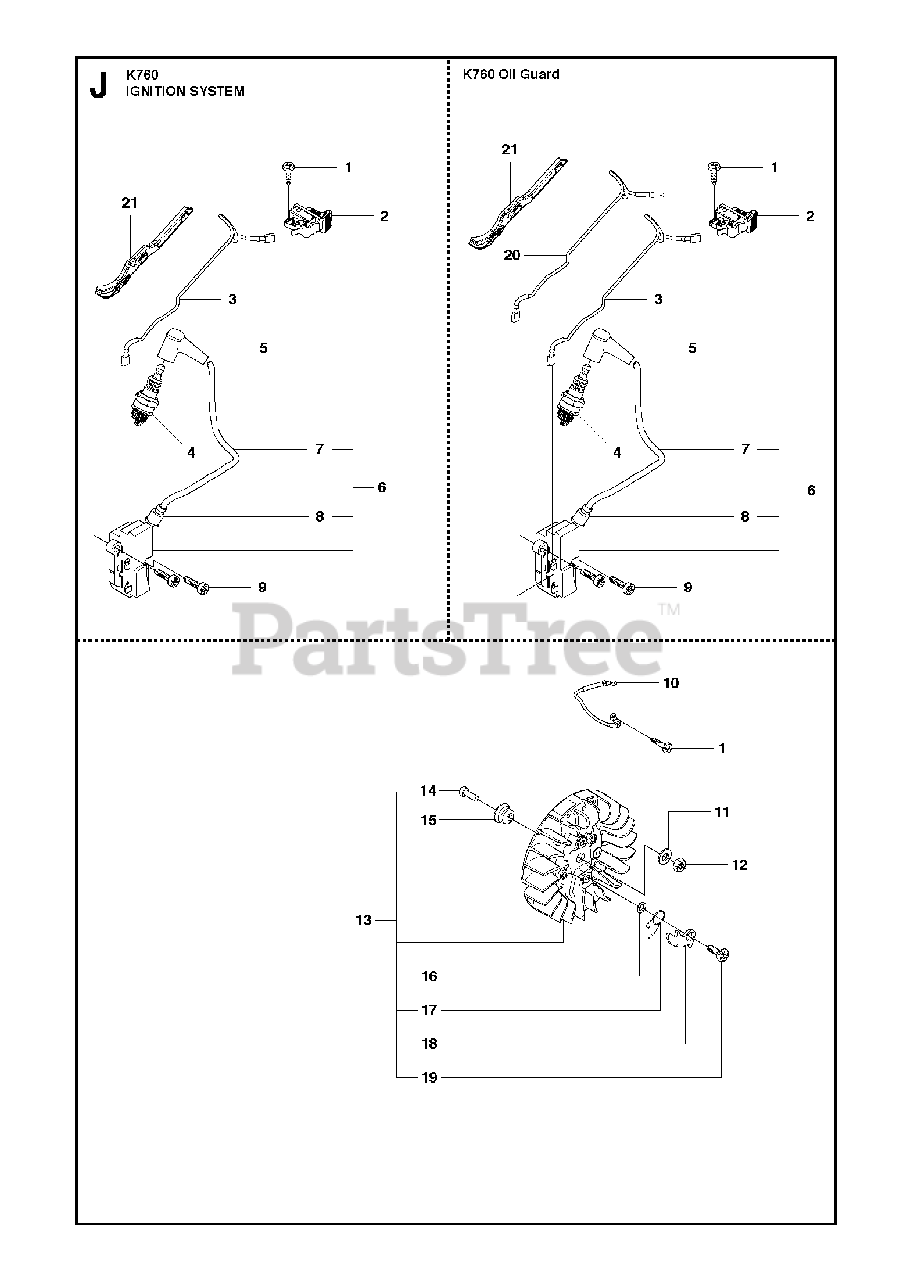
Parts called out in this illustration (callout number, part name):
1	SCREW CCRPANT
2	STOP SWITCH
3	CABLE
3	CABLEOil Guard
4	SPARK PLUGRCJ 6 Y
5	SPARK PLUG CAP
6	IGNITION MODULEIncl. 7 - 8
7	IGNITION CABLE
9	SCREW ITXSCM
13	FLYWHEELIncl. 14 - 19
14	SCREW IHSCM
19	SCREW
20	CABLEOil Guard
21	CABLE HOLDER
